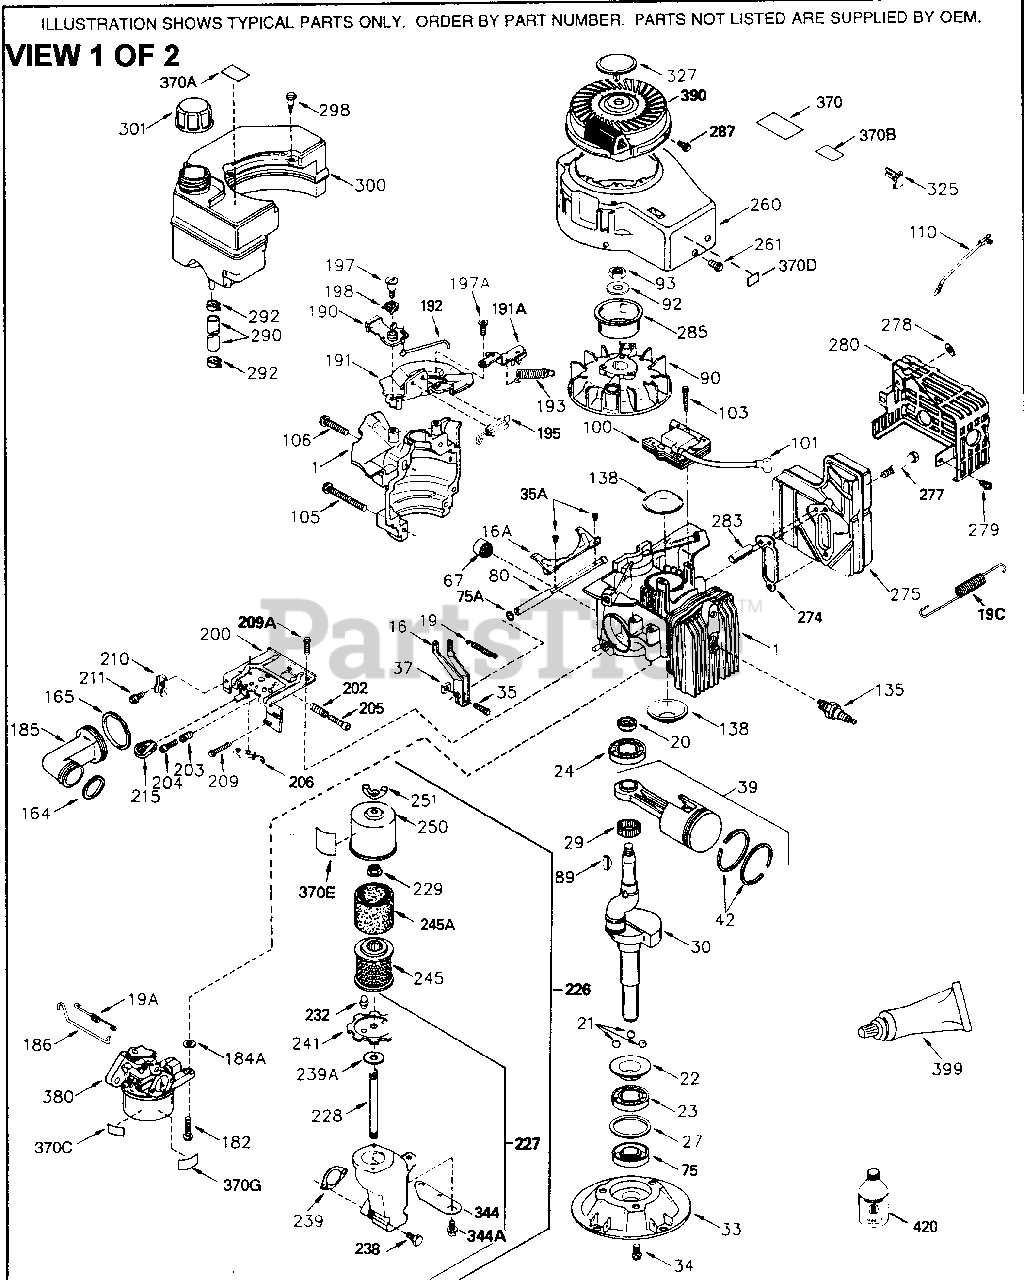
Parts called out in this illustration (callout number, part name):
1	"Cylinder Incl. 67A, 75, 105, 106 & 1 38
16	Governor Lever
16A	Governor Follower Arm
19	Extension Spring
19A	Throttle Link Spring
20	Oil Seal
21	Ball Bearing
22	Slide Ring
23	Ball Bearing
24	Ball Bearing
27	Bearing Retainer
29	Bearing Strip (31 needles) .495" lon g
30	Crankshaft
33	Adapter Plate
34	Screw, 5/16-18 x 1"
35	Screw, 10-32 x 3/4"
35A	Screw, 4-40 x 3/16"
37	Lock Nut, 10-32
39	Piston & Rod Ass'y. (Incl. 29 & 42)
42	Ring Set
67	Fuel Filter (Screen w/brass collar)
67A	Fuel Filter (Screen) (Optional)
75	Oil Seal (P.T.O. end)
75A	Oil Seal
80	Governor Shaft
89	Flywheel Key
90	Flywheel (Counterbalance)
92	Belleville Washer
93	Flywheel Nut
100	Solid State Ignition
101	Spark Plug Cover
103	Screw, Torx T-15, 10-24 x 1"
105	Screw, 5/16-18 x 2-3/16"
106	Screw, 5/16-18 x 1-5/8"
110	Ground Wire
135	Spark Plug (RCJ8Y)
138	Port Cover
164	"O" Ring
165	"O" Ring
182	Screw, 5/16-18 x 1"
184A	Washer
185	Intake Pipe & Reed Ass'y. Incl. 164 & 165
186	Governor Link
200	Control Bracket Incl. 203, 205 & 206
202	Compression Spring
203	Compression Spring
204	Screw, 5-40 x 7/16"
205	Screw, 10-32 x 1-1/8"
206	Terminal
209	Screw, 10-24 x 3/4"
215	Control Knob
226	Air Cleaner Kit Incl. 227, 229, 238, 239, 245, 245A, 250, 251 & 370B
227	Air Cleaner Elbow Ass'y. Incl. 228, 2 32, 238, 239A, 241, 344 & 344A
228	Stud, 1/4-20 x 4.89 threaded both en ds
229	Nut & Lock Washer, 1/4-20
232	Pop Rivet (Can be purchased locally)
239	Air Cleaner Gasket
239A	Air Cleaner Gasket
241	Air Cleaner Bracket
245	Air Filter
245A	Air Filter
250	Air Cleaner Cover
251	Wing Nut, 1/4-20
260	Blower Housing
261	Screw, 5/16-18 x 5/8"
274	Exhaust Gasket
277	Screw, 5/16-18 x 3-13/64"
279	Screw, 10-32 x 1/4"
280	Heat Shield
283	E.G.R. Tube
285	Starter Cup
287	Screw, 8-32 x 21/64"
290	Fuel Line (8.62")
292	Fuel Line Clamp
327	Starter Plug
370	Fuel Mix Decal
370A	Name Decal
370B	Instruction Decal
370C	Bowl Nut Decal
370D	Primer Decal
370G	Speed Control Decal
380	Carburetor (Incl. 164) (Refer to Divi sion 5, Section A, page A6-2 or Fiche 25, Grid F-1for breakdown)
390	Rewind Starter Refer to Division 5, S ection C, page 34 or Fiche 25, Grid G -1 for breakdown
399	Gasket Eliminator (Loctite 515)
420	2-Cycle Oil with Fuel Stabilizer - 8 oz.
